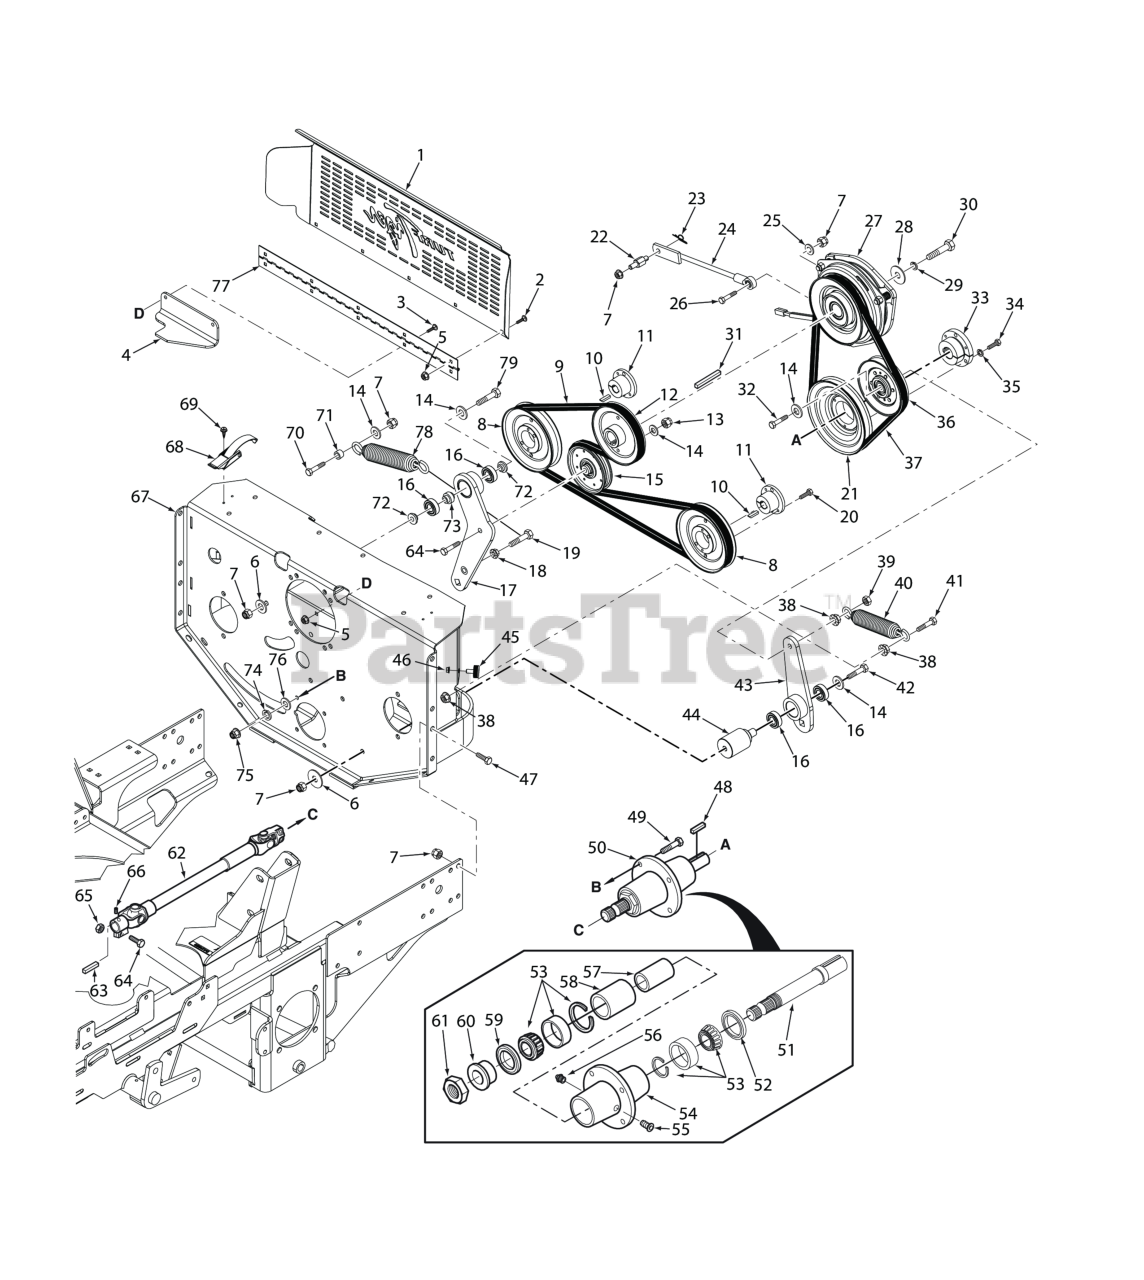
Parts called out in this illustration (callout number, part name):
1	Cover, Rear
2	Bolt, Carriage 1/4-20 x 1/2"
3	Serr. Fl. Hex Head CPSCR, 1/4-20 x 3/4"
4	Bracket, Idler Stop
5	NUT, 1/4-20 SERRATED FLANGE HEX HEAD
6	Flatwasher, 3/8-.406 x 1-1-1/2 x 7 Gauge
7	HEX NUT, ELASTIC STOP LOCK, 3/8-16
8	Pulley, 5.75 O.D. (Gasoline Engines)
9	Belt, STTII Pump Drive (Gasoline Engines)
10	Key, 5mm x 5mm x 30mm
11	Tapered Hub, 17mm Bore
12	Pulley, 5.67 O.D. (Kawasaki & Kohler Only)
13	Bolt, Hex Head 3/8-16 x 1" Ser. Flg.
14	Flatwasher, 3/8 (.391 x .938 x .105 HD) Grade 8
15	Pulley, Idler 4� Dia.
16	BEARINGS, BALL, NEUTRAL RETURN
17	Idler Arm Assy.
18	Nut, Hex Serrated Flange 1/2-13
19	Bolt, Hex Head 1/2-13 x 2� Grd 8
20	Bolt, Hex Head 1/4-20 x 1" Grade 8 Black
21	Pulley, 6.70" O.D. Tapered Bore
22	STUD, ANTI-ROTATION
23	Pin, Rue Cotter 3/8" Diameter
24	Rod Assembly, Clutch Anti-Rotation
25	Flatwasher, 3/8-.438 x 1.00 x .083
26	Bolt, Hex Head 3/8-16 x 1-1/4", Kawasaki FX / FT & FT-EFI
27	Electric Clutch w/Tag - GT-3.5 (FX850)
28	Flatwasher, 7/16-.469 x 1.75 x .25 (48, 52)
29	Lockwasher, 7/16� Spring
30	Bolt, Hex Head 7/16-20 x 2-1/2" (Kohler)
31	Key, 1/4 x 1/4 x 3-1/4�
32	Bolt, Hex Head 3/8-16 x 2-1/2" 1.5 Thread Grd.8
33	Tapered Hub, 1.00 Bore
34	BOLT, HEX HEAD, 1/4-20 X 1-3/8(FULL THREAD)
35	Lockwasher, 1/4� Spring
36	IDLER PULLEY, "V" GROOVE
37	Belt, Pump Drive - Kubota
38	NUT, 3/8-16 SERRATED FLANGE HEX HEAD
39	Bolt, Hex Head 3/8-16 x 1" Ser. Flg.
40	Spring, PTO (Gasoline Engines)
41	Bolt, Hex Head 3/8-16 x 1-1/2" Grade 8 Black
42	Bolt, Hex Head 3/8-16 x 4-1/2" Grade 8 Black
43	Idler Arm Weldment, PTO Drive
44	Pivot, Idler - PTO
45	Bumper, Rubber 5/16-18 x 5/8"
46	Nut, Serrated Flange 5/16-18 (Right Front Engine Mounting, Briggs and Kohler Only)
47	Bolt, Hex Head, 3/8-16 x 1 Gr. 5
48	KEY 1/4 X 1/4 X 1 1/2"(FOR 1" CRANKSHAFT
49	Bolt, Hex Head 5/16-18 x 1-3/4" Grade 8
50	Spindle Assembly, Deck Drive
51	Shaft, Deck Drive
52	SEAL, 2.00 O.D. X 1.50 BORE
53	Tapered Bearing Set (Two Bearings W/Race)
54	Housing, Spindle
55	RELIEF FITTING, TAPERED BEARING SPINDLE
56	GREASE FITTING, STR. 1/4-28 SELF TAP.
57	SLEEVE, CUTTER SPINDLE
58	Spacer, Outside, Cutter Spindle
59	Seal, 2.00" O.D. x 1.625" Bore
60	SPINDLE BUSHING, BOTTOM
61	Nut , Spec ial 1 -1/ 1 6 - 1 8
62	Driveshaft (Air Cooled Engine)
63	Key, 1/4" x 1/4" x 1" Clutch Mtg.
64	Bolt, Hex Head 3/8-16 x 1-3/4" (Kohler EFI)
65	Bolt, Hex Head 3/8-16 x 1" Ser. Flg.
66	Set Screw, 3/8-16 x 1/2" Internal Hex
67	Pump Mounting Plate Weldment (Gasoline)
68	LATCH, HOOD
69	Screw, #10-32 x .563 Shakeproof
70	Bolt, Hex Head 3/8-16 x 1-1/2" B&S 32BV
71	Spacer, Spring Anchor
72	Spacer, Controls
73	Spacer, Bearing
74	Lockwasher, 5/16 (.317 x .586 x .078) Helical Spring
75	Lock Nut, 5/16-18 Elastic Stop Grade 8
76	Flatwasher, 5/16-.375 x .875 x .083 (35BV & 37BV-EFI)
77	Hinge, Rear Belt Guard
78	Spring, PTO (Gasoline Engines)
79	Capscrew, Hex Head 3/8-16 x 2.75"
